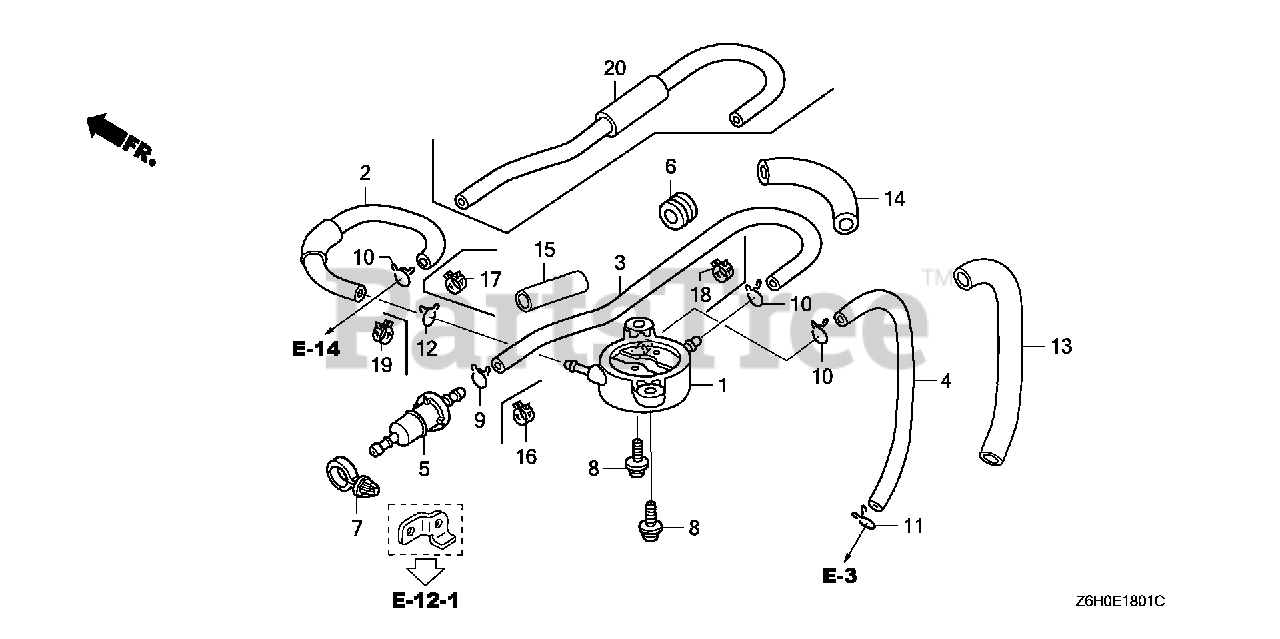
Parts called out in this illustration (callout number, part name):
1	PUMP ASSY., FUEL
2	TUBE, FUEL (FKM)
4	TUBE, DIAPHRAGM
5	STRAINER, FUEL
6	GROMMET, RESERVE TANK
7	CLIP, WIRE HARNESS
8	SCREW-WASHER (6X16)
10	CLIP, TUBE (B10)
11	CLIP, TUBE (B8)
13	BULK HOSE, VINYL (9X11X3000) (9X11X150)
14	BULK HOSE, VINYL (11X13X3000) (11X13X50)
15	BULK HOSE, VINYL (11X13X3000) (11X13X30)
16	CLAMP, TUBE (D8)
17	CLAMP, TUBE (D10)
18	CLAMP, TUBE (D8.5)
19	CLAMP, TUBE (D10)
20	TUBE B, FUEL (FKM)
